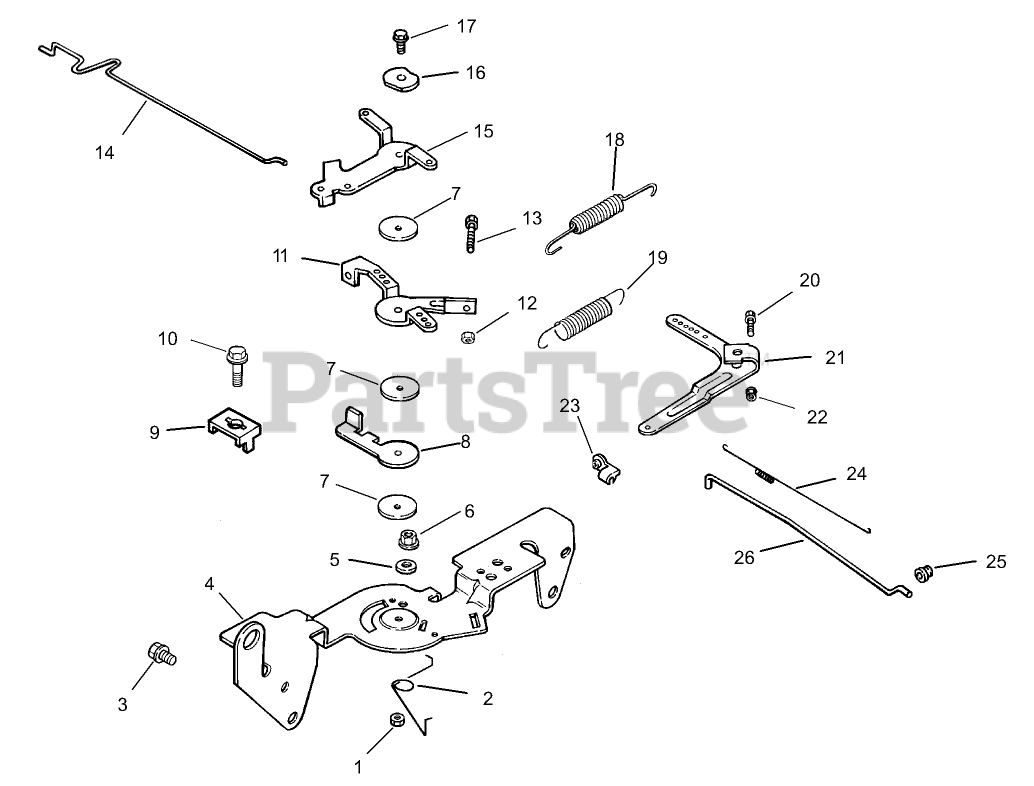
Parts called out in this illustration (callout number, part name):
1	NUT-LOCK (M5X.8)
2	SPRING-RETURN, CHOKE
3	SCREW-FLANGE, THREAD FORMING (M6X1.0X16)
4	Bracket-Control
5	Washer-Lock (.25)
6	Nut-HF (M5x0.8)
7	WASHER-FLAT (5.5MM)
8	Lever-Actuator, Throttle
9	CLAMP-CABLE
10	SCREW-FLANGE, THREAD FORMING (M5X0.8X16)
11	Lever-Control, Throttle
12	NUT (M4X0.7)
13	Screw (M4x0.7x30)
14	Linkage-Choke
15	LEVER-CHOKE
16	WASHER-SPRING (1/4)
17	SCREW-FLANGE, THREAD FORMING (M5X.8X20)
18	Spring-Limiter, Throttle
19	Spring-Governor (ORANGE)
20	BOLT-SQ NECK, RD HD (M6X1.0X25)
21	Lever-Governor
22	NUT-FLANGE (M6X1.0)
23	BUSHING-RETAINING, LINKAGE
24	SPRING-LINKAGE
25	BUSHING-LINKAGE, THROTTLE
26	Linkage-Throttle
